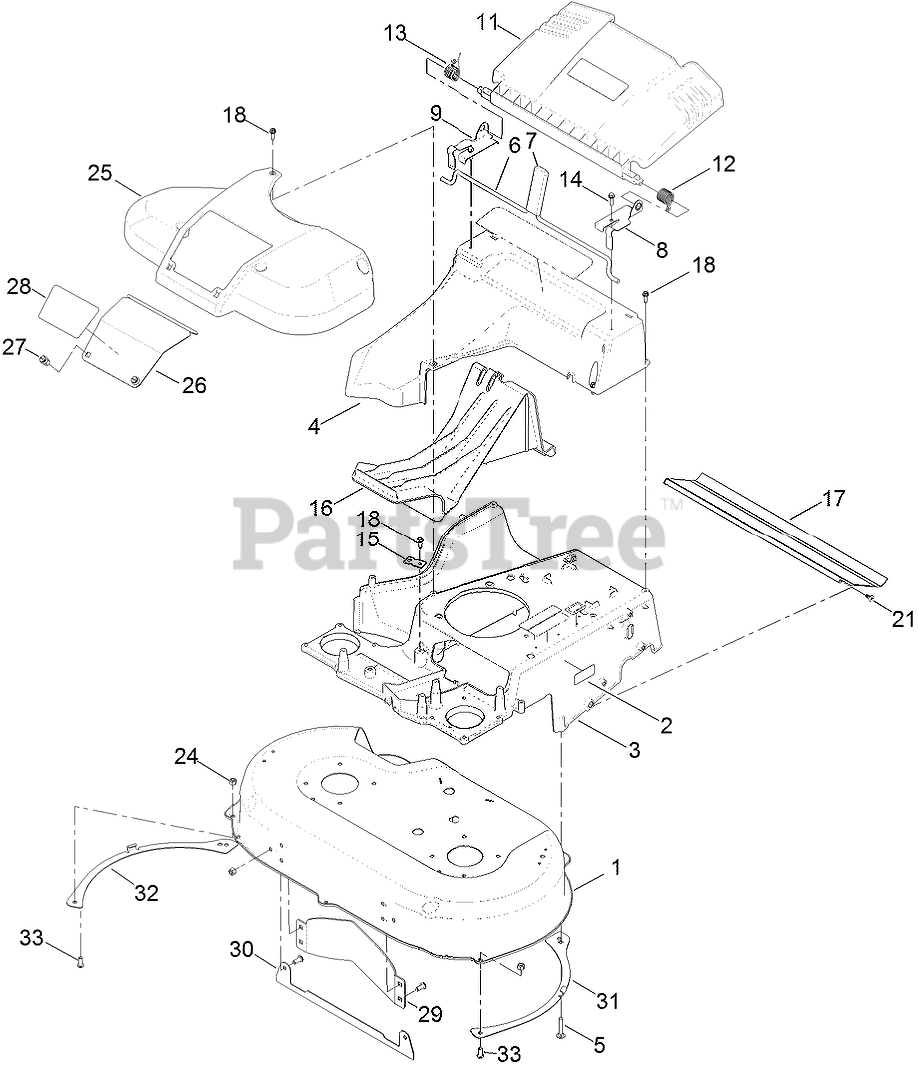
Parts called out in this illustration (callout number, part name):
1	HOUSING ASM
2	DECAL-LOCATION, SERVICE DEALER
4	CHUTE
5	SCREW-CARR
6	ROD-RELEASE, HANDLE
7	GRIP-LEVER
8	BRACKET-DOOR, LH
9	BRACKET-DOOR, RH
11	REAR DEFLECTOR ASM
12	SPRING-TORSION
13	SPRING-TORSION
14	SCREW-HWH
15	BRACKET-CABLE, TRACTION
16	PLUG-MULCH
17	SHIELD-TRAILING
18	SCREW-HWHTF
21	SCREW-PTH
24	NUT-LOCK, NI
25	COVER-BELT
26	DOOR-ACCESS
27	FASTENER
28	DECAL-ACCESS PANEL
29	BAFFLE-FLOW, CONTROL
30	PLATE-DECK
33	SCREW-HSBH
